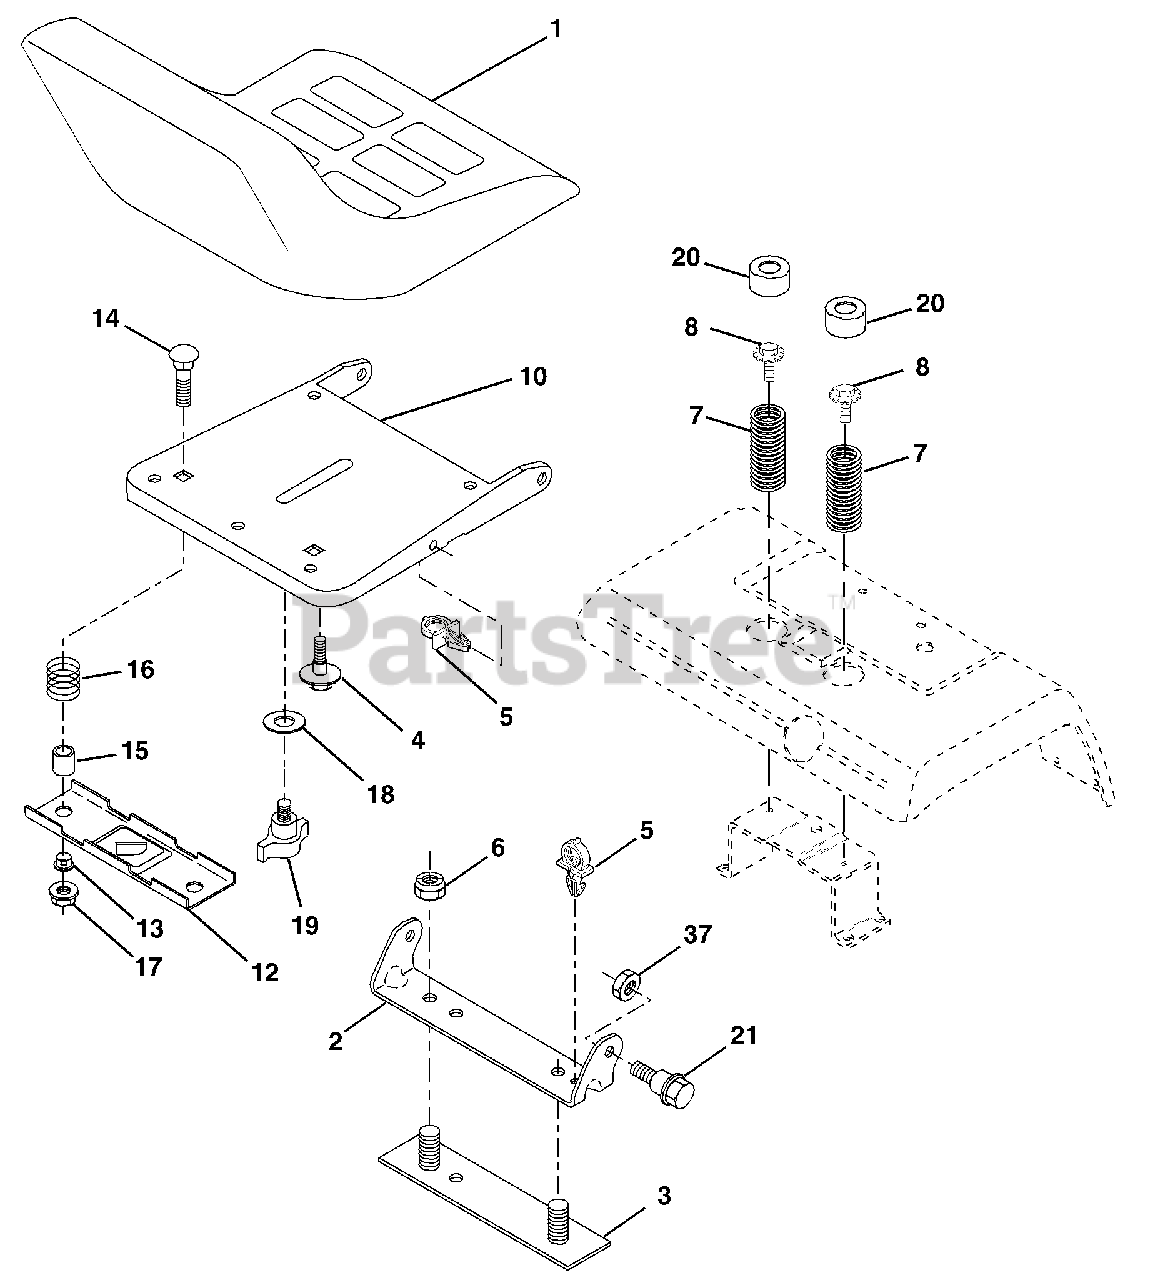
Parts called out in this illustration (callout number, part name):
1	Seat
2	Bracket Pivot Fender
3	Strap, Fender Assy.
4	Bolt Shoulder 5/16-18 x .62
5	Clip, Push In, Hinged
6	Nut, lock 3/8-16 Unc
7	Spring, Seat Cprsn
8	Bolt 5/16-18 Unc x 3/4 w/Sems
10	Pan, Seat
12	Bracket, Mounting Switch
13	Bushing, Snap
14	Bolt, Carriage 1/4-20 x 1-1/2
15	Spacer, Split
16	Spring, Cprsn
17	Nut, Lock 1/4 Lge Flg Gr. 5
18	Washer 17/32 x 1-3/16 x 12 Ga.
19	Knob, Seat
20	Cap, Spring Seat
21	Bolt, Shoulder 5/16-18
22	Nut, Crownlock 5/16-18 Unc
